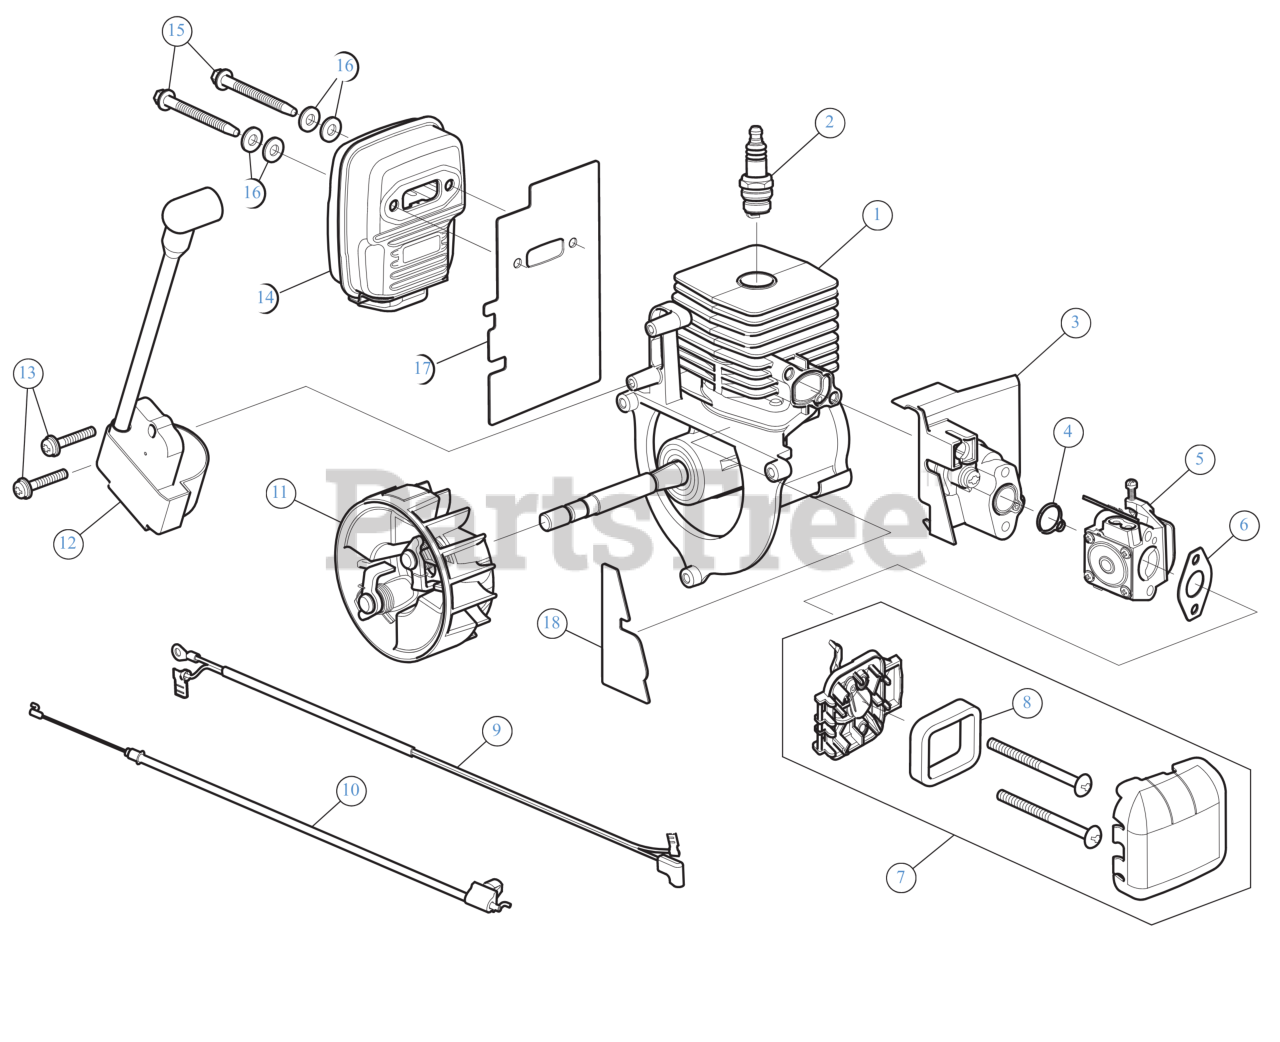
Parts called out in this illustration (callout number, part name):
1	SHORT BLOCK
2	SPARK PLUG
3	INTAKE ASSEMBLY
4	O-RING
5	CARBURETOR
6	GASKET CARB
7	AIR CLEANER ASSEMBLY
8	AIR FILTER
9	WIRE LEAD
10	THROTTLE CABLE
11	FLYWHEEL ASSEMBLY
12	MODULE
13	SCREW 8-32X.750
14	MUFFLER ASSEMBLY
15	MUFFLER SCREW
16	WASH, FLAT .480X.1
17	GASKET
18	SHORTBLOCK GASKET
